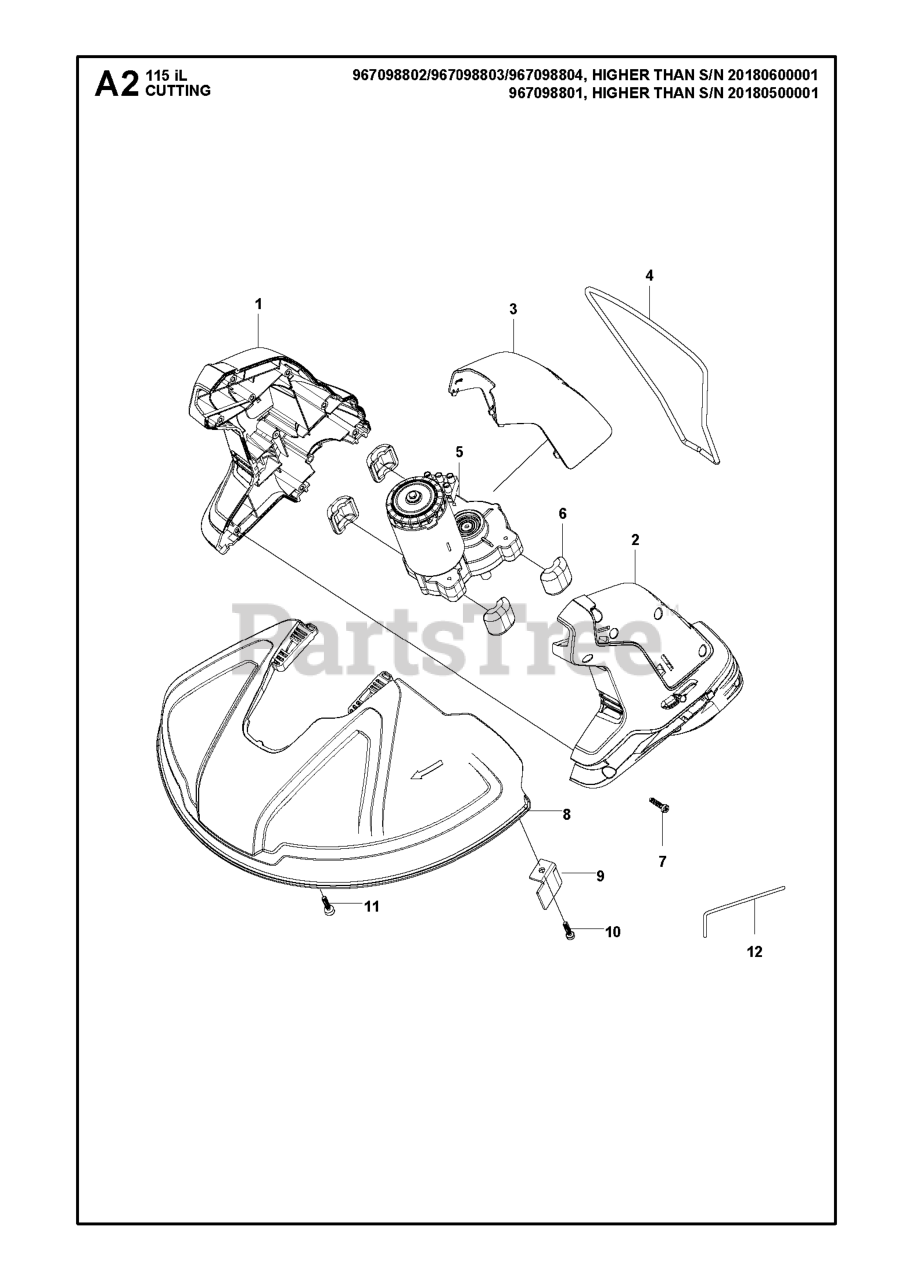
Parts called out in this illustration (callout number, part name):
1	HOUSING MOTOR HOUSING L 36V
2	HOUSING MOTOR HOUSING R 36V
3	COVER MOTOR HOUSING
4	RING PLANT GUARD
5	GEARBOX ASSY 115IL TRIMMER
7	SCREW ST4X16
8	GUARD FOR CUTTING HEAD
9	BLADE 330MM
10	SCREW ST4X16
11	SCREW ST4*16
